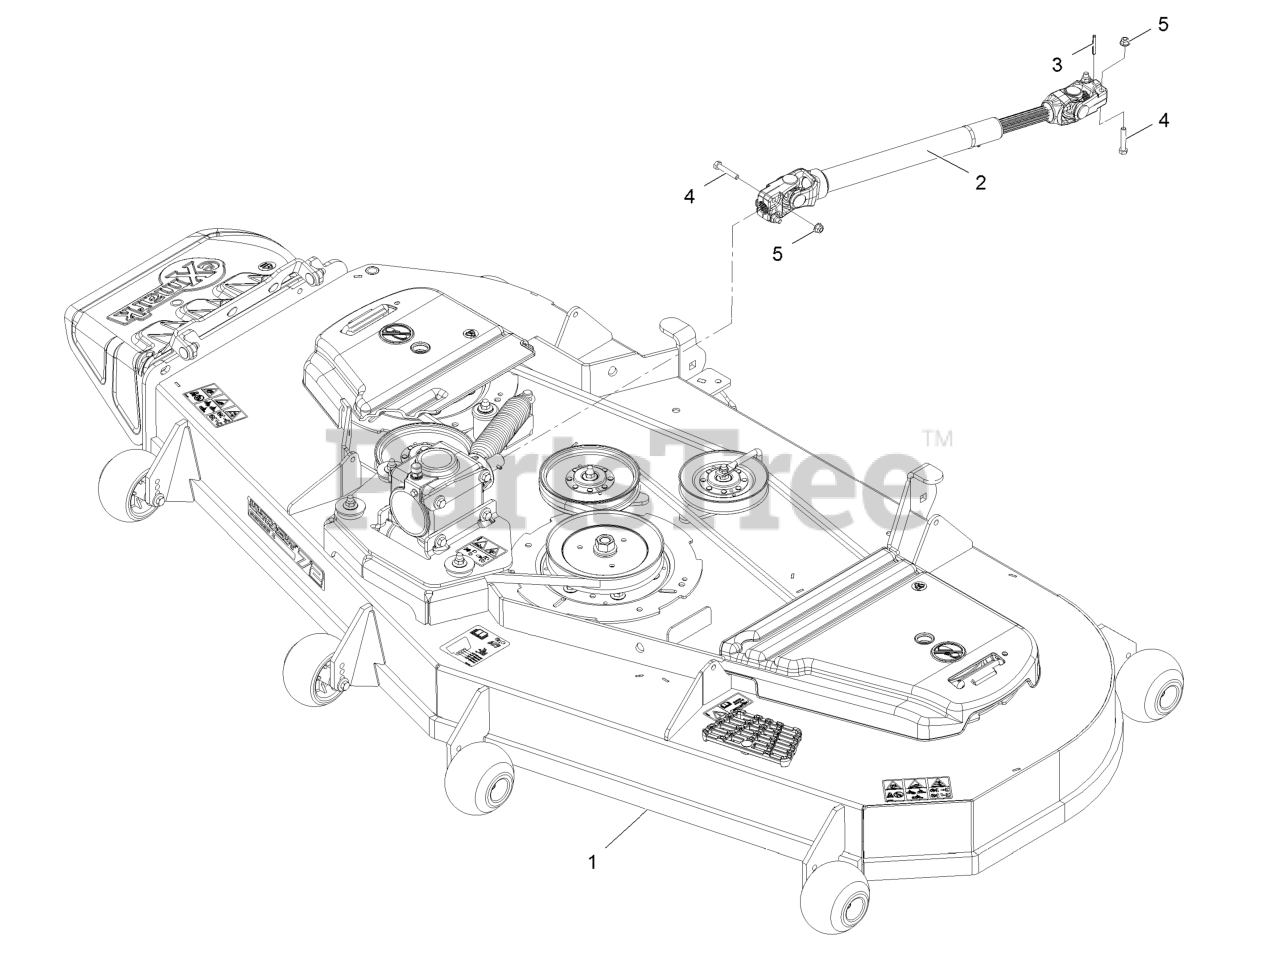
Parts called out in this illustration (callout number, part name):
1	Deck ASM-724
2	Driveshaft ASM
3	Pin-Roll
4	Screw-HH 5/16-18 X 1 3/4
5	Nut-Nyloc 5/16-18 Flg
